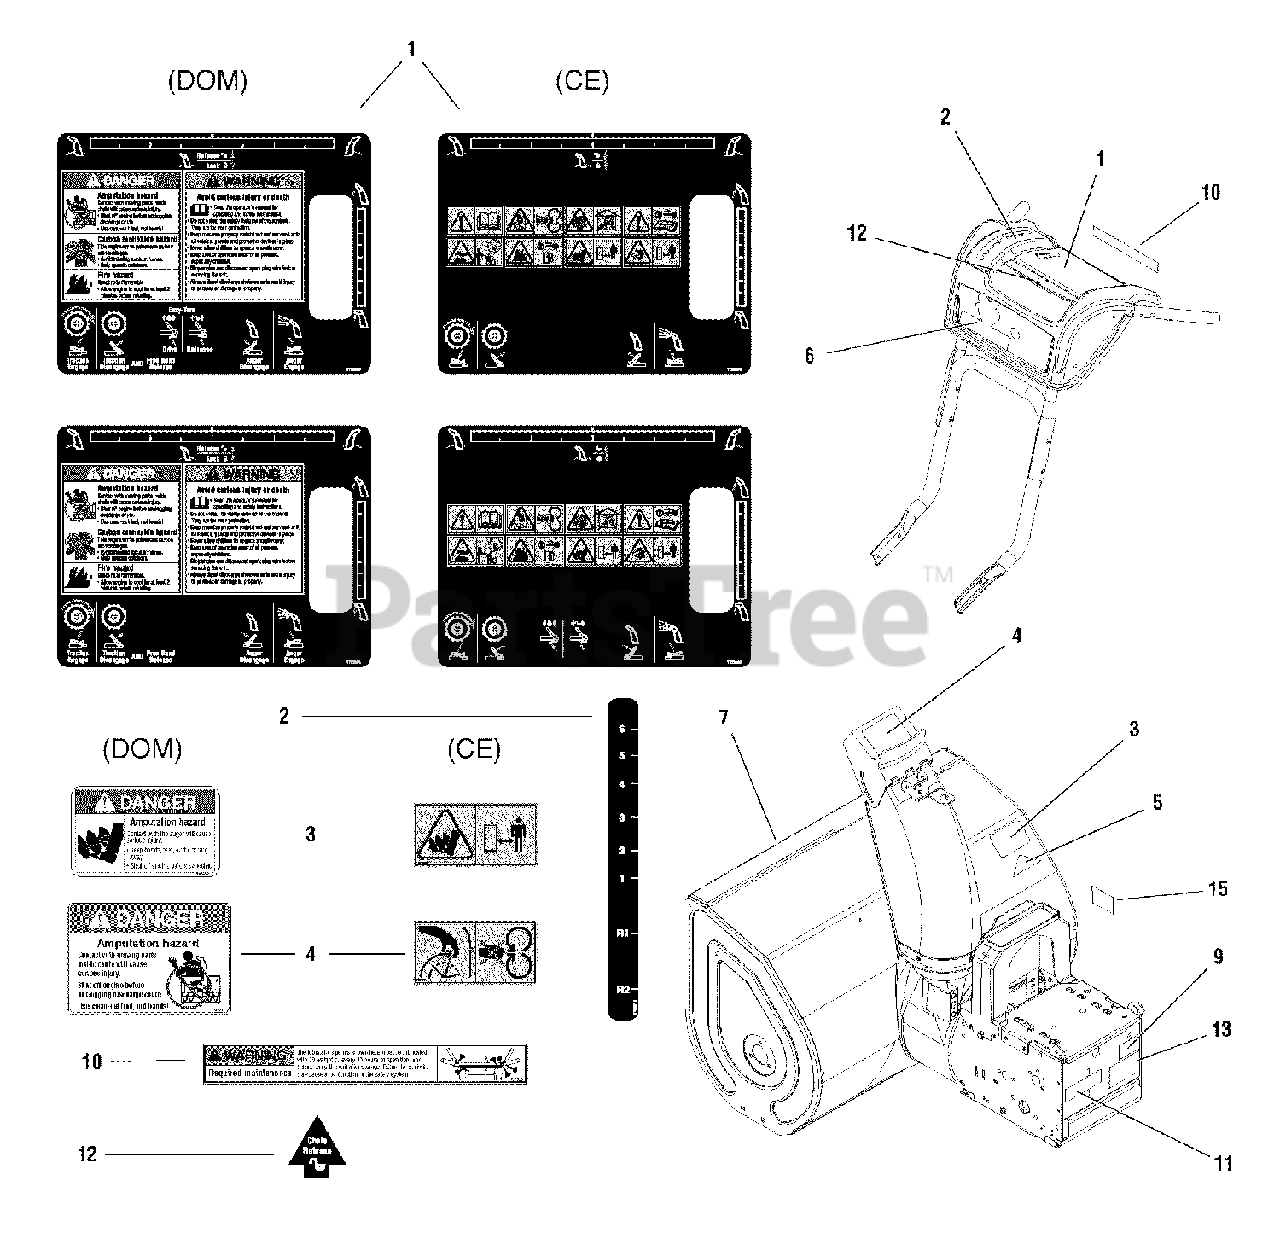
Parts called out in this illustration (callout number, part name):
1	DECAL, Dashboard Standard Drive
1	DECAL, Dashboard EZ Turn
2	DECAL, Shift 1,2,3,4,5,6 R1 R2
3	DECAL, Danger Avoid Injury From Auger
3	DECAL, Impeller Warning
4	DECAL, Danger Amputation Hazard
4	DECAL, Chute Warning
5	DECAL, Opei Certified ANSI
6	DECAL, Snapper, Turtle
7	DECAL, Snapper 9528L, Stripe
7	DECAL, Snapper 8526L, Stripe
7	DECAL, Snapper 10530L, Stripe
7	DECAL, Snapper 11532L, Stripe
9	DECAL, Over Adjustment of Friction Disc
10	DECAL, Warning Lubrication
11	DECAL, Touch Up Paint Orange, Black, Red
12	DECAL, Chute Release Arrow
13	DECAL, ID Plate
15	DECAL, Belt Stretch & Adjustment
